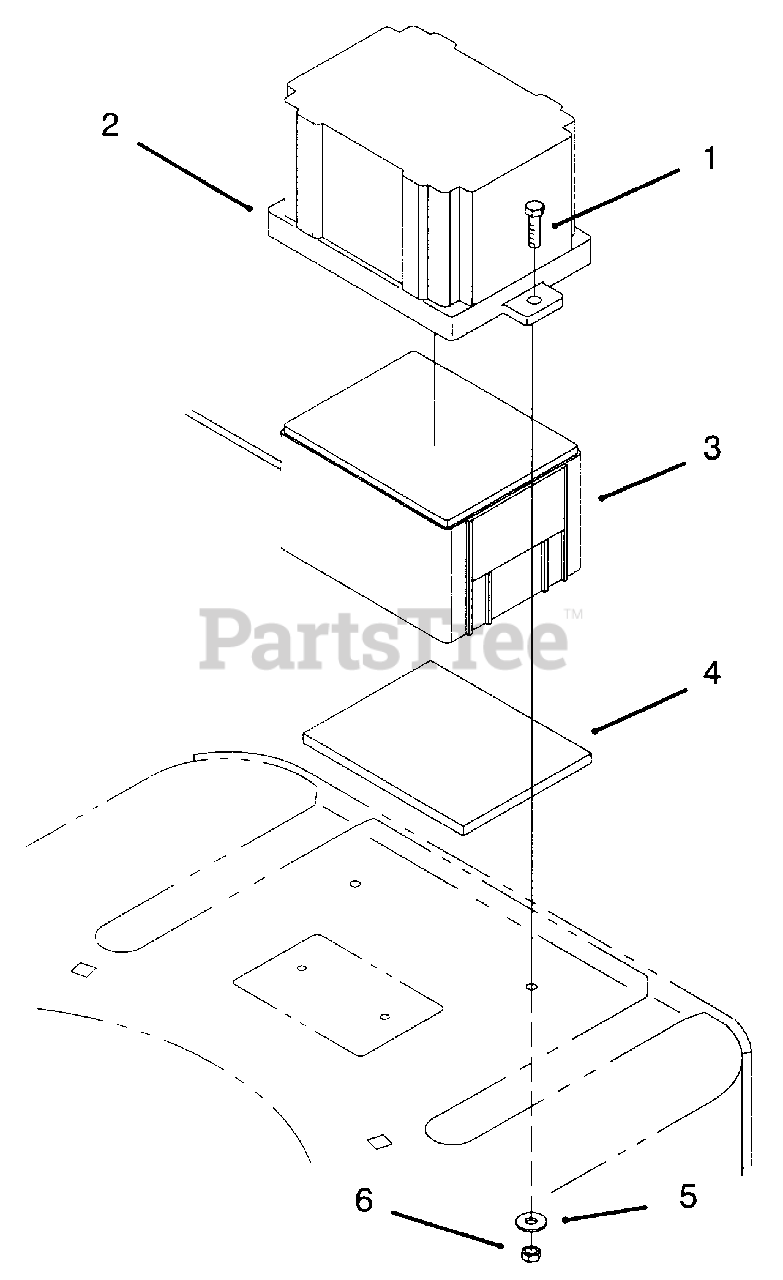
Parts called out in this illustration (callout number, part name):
1	Screw
2	Case-Battery
3	Battery Pack
4	Pad Battery
